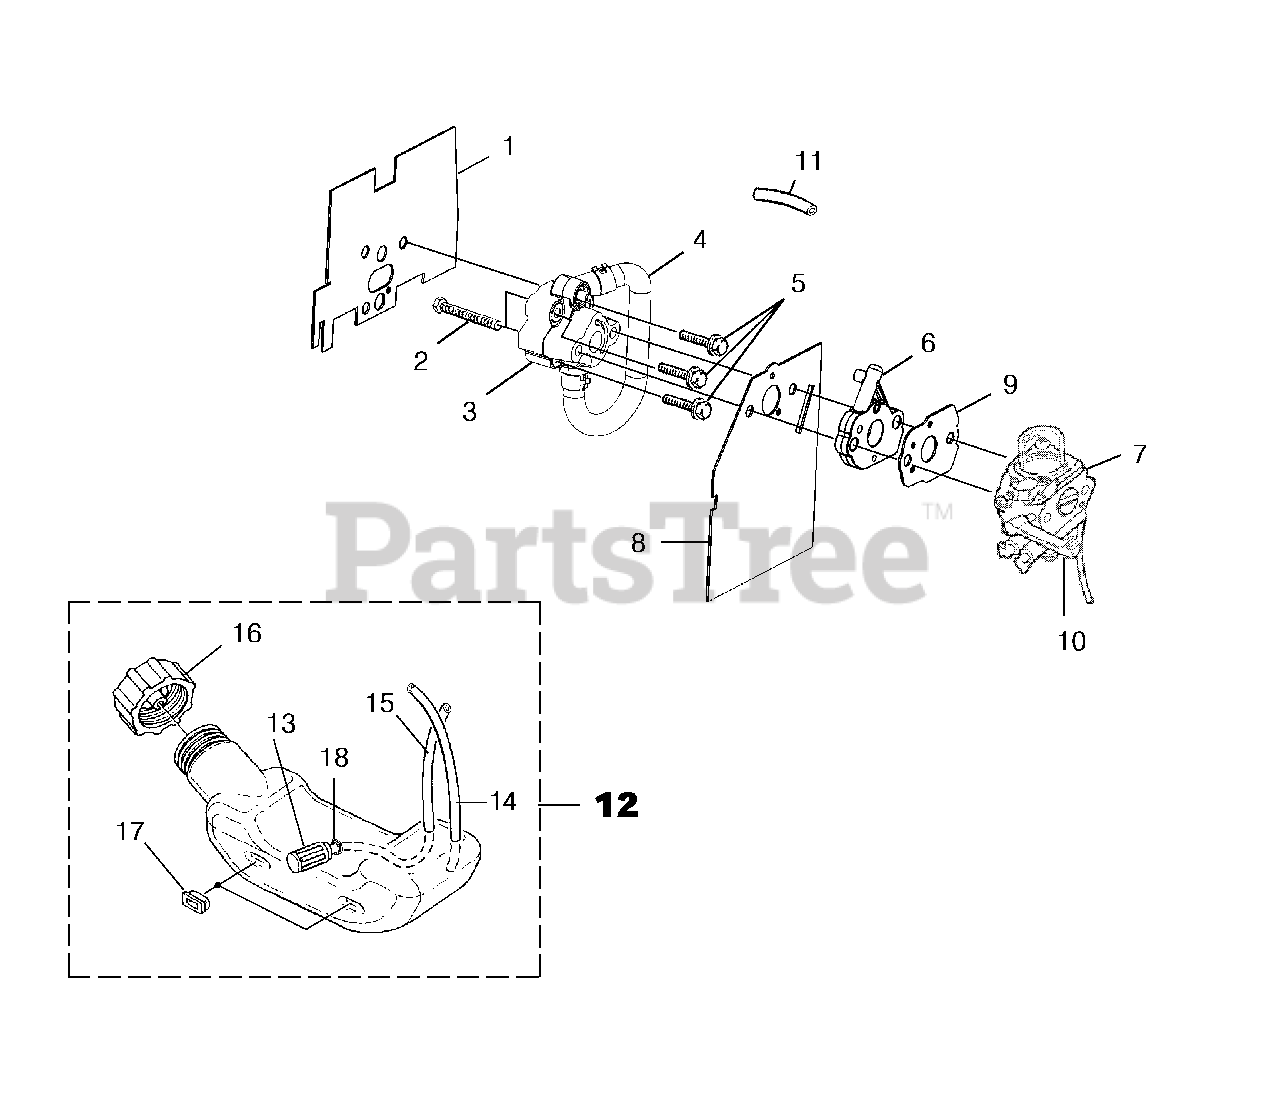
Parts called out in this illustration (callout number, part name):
1	GASKET-Heat Dam to Cylinder
2	SCREW-Shoulder
3	HEAT DAM Complete
4	TUBE-Tuned
5	SCREW-Sems (10-24 x 1")
7	CARBURETOR KIT (Non Clutch)
7	CARBURETOR KIT (Clutch)
8	GASKET-Adaptor to Heat Dam
9	GASKET-Carburetor to Adaptor
10	LEVER-Choke
11	TUBE-Rubber
12	FUEL TANK ASSY.
13	FILTER-Fuel
14	TUBING-Rubber (5.5")
15	TUBING-Rubber (7.25")
16	FUEL CAP
17	BUMPER-Rubber
18	CLAMP
